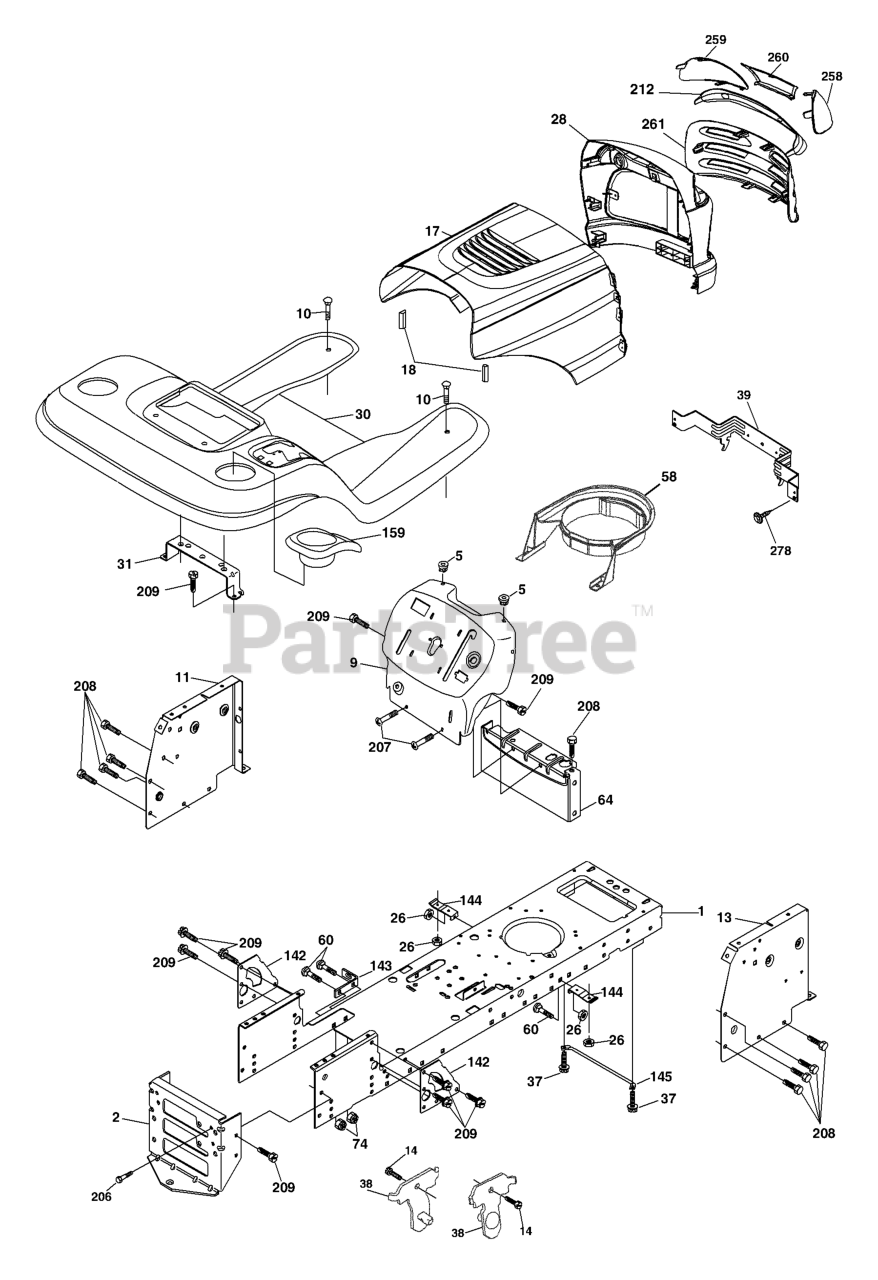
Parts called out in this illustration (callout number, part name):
1	CHASSIS STAMPING
2	DRAWBAR, 12GA
5	BUMPER.RUBBER.HOOD
9	DASH PANEL
10	BOLT D
11	PANEL.DASH.LH.LTX
13	PANEL DASH RH
14	SCREW LT
17	HOOD
18	BUMPER.HOOD.LARGE.1.75"
20	PLATE MTG.BATTERY/FUEL TANK
23	BUSHING.SNAP.NYL.BLK.
26	NUT
28	GRILL/LEN.ASM.DL.HUSQ
30	FENDER W/ CUP HOLDER
31	BRACKET.SUPPORT.FENDER
37	Screw Thdrol 5/16-18 x 1/2
38	BRACKET.ASM.PIVOT.MOWER.REAR
39	BRACKET PIVOT LASER
60	Bolt RDHD SQNK 3/8-16 x 3/4
64	DASH LOWER
142	PLATE REINFORCEMENT
143	BRACKET, SWAYBAR CHASSIS
144	BRKT, FOOT REST
145	ROD PIVOT CHASSIS/HOOD
159	CUPHOLDER
206	SHOULDER BOLT 5/16-18TT
207	SCREW, 5/16-18 X 1/2
208	SCREW 3/8-16X1/2
209	SCREW, 3/8-16X3/4
212	INSERT.LENS.REFLECTIVE
219	SCREW
258	LENS LH
259	LENS LH
260	COVER.LENS.HUSQ.( HAVE GRAY)
261	INSERT GRILLE
278	Screw 10 x 3/4 Single Lead-Hex
